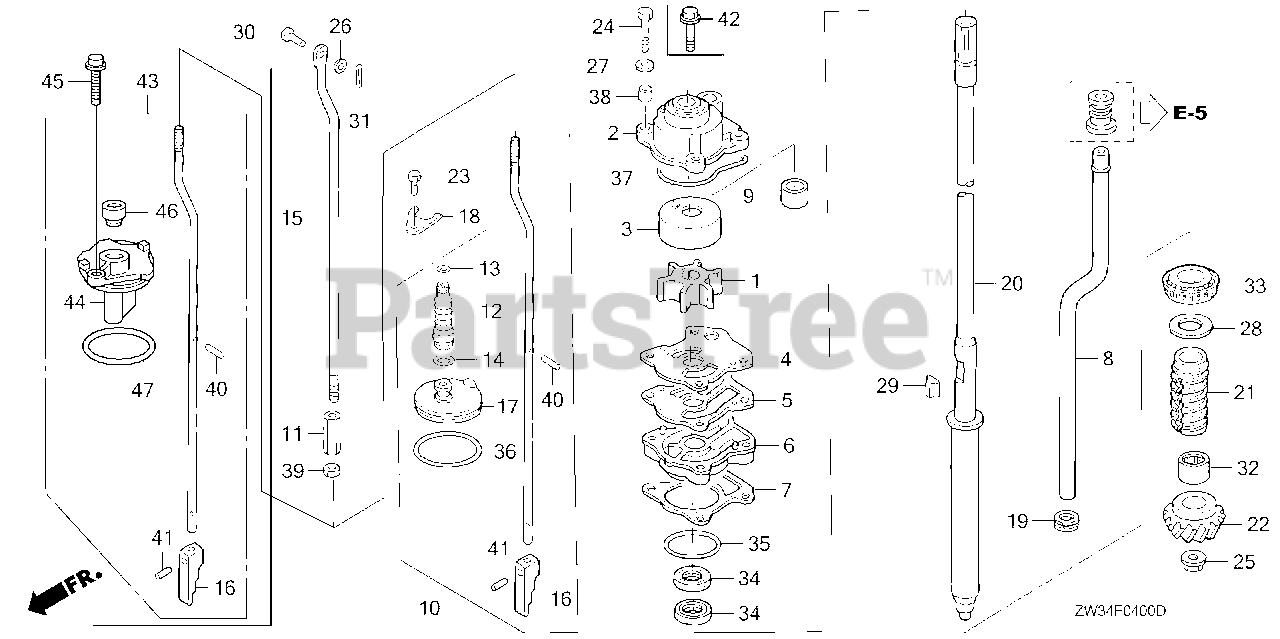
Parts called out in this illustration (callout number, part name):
1	IMPELLER, PUMP
2	HOUSING, IMPELLER
3	LINER, PUMP
4	COVER, IMPELLER
5	GASKET B, IMPELLER
6	HOUSING, WATER PUMP
7	GASKET, WATER PUMP
8	TUBE, WATER (L)
9	RING, WATER TUBE SEAL
10	ROD, SHIFT (L)
11	JOINT, SHIFT ROD
12	GROMMET, SHIFT ROD
13	BAND A, GROMMET
14	BAND B, GROMMET
15	ROD A, SHIFT
16	ROD, PUSH
17	HOLDER, SEAL
18	PLATE, SEAL HOLDER SETTING
19	GROMMET, EXTENSION CASE
20	SHAFT, VERTICAL (L)
21	SLINGER, OIL
22	GEAR, PINION
23	BOLT, HEX. (6X12)
24	BOLT, HEX. (6X40)
25	NUT, SPECIAL (12MM)
26	WASHER, PLAIN (5MM)
27	WASHER (6MM)
28	SHIM, GEAR (40X46X0.10) (A)
28	SHIM, GEAR (40X46X0.15) (B)
28	SHIM, GEAR (40X46X0.30) (C)
28	SHIM, GEAR (40X46X0.50) (D)
29	KEY, WOODRUFF
30	PIN (5X17)
31	PIN, SPLIT (1.6MM)
32	BEARING, NEEDLE (7/8X11/8X1)
33	BEARING (25X47X15)
34	SEAL, WATER (17X30X7)
35	O-RING (41.7X3.5)
36	O-RING (47X3.1)
37	O-RING, WATER PUMP
38	COLLAR, IMPELLER HOUSING
39	NUT, HEX. (8MM)
40	PIN, SPRING (2X12)
41	ROLLER (3X14.8)
